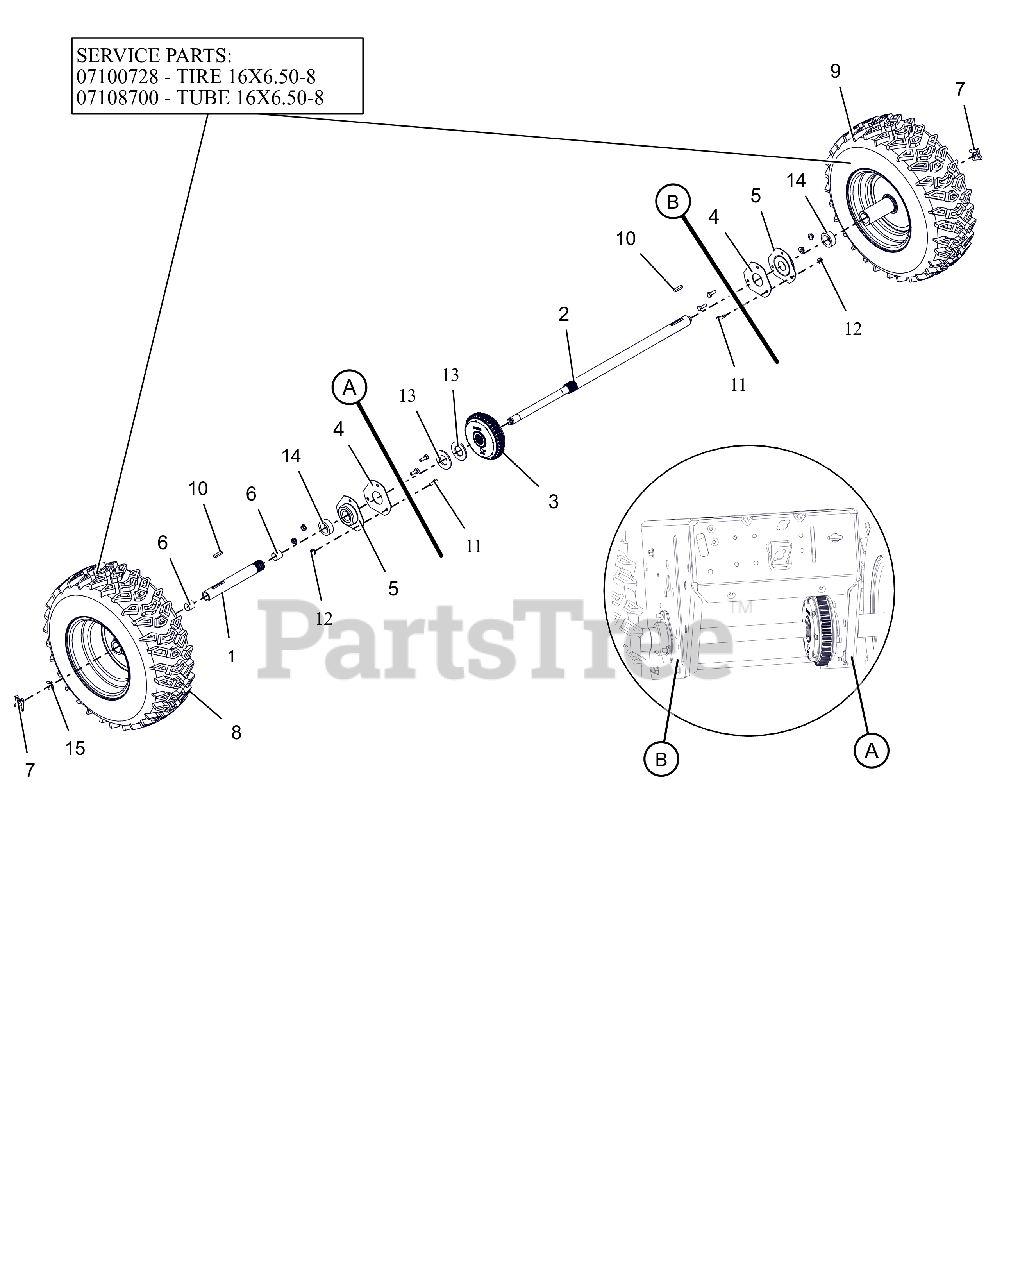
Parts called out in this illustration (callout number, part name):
1	AXLE, SHORT-AUTO W/BUSHINGS
2	AXLE, LONG-PRO AUTO DIFF
3	DIFFERENTIAL, AUTOMATIC
4	PLATE, BEARING SPACER
5	BRG-FLG 1.003/1.000 3 BOLT
6	BSHG-SLV .706X.764X.75 BRZ
7	CLIP, SNAP .625 DIA
8	TIRE/WHEEL,RH 16X6.5-8 DIFF T2
8-9	TIRE, 16X6.50-8 K478
8-9	TUBE
9	TIRE/WHEEL,LH 16X6.5-8 DIFF T2
10	KEY-RECT .25X.188X1.00
11	BLT, HEX .25-20X.75 G5 ZCC
12	NUT-LK-CTR-FLG .25-20 ZC120
13	WSHR, FLT 1.062X2.000X.134 ZCC
14	SPACER, PRO AXLE BEARING
15	RG-RTNG-EXT .625X.042
